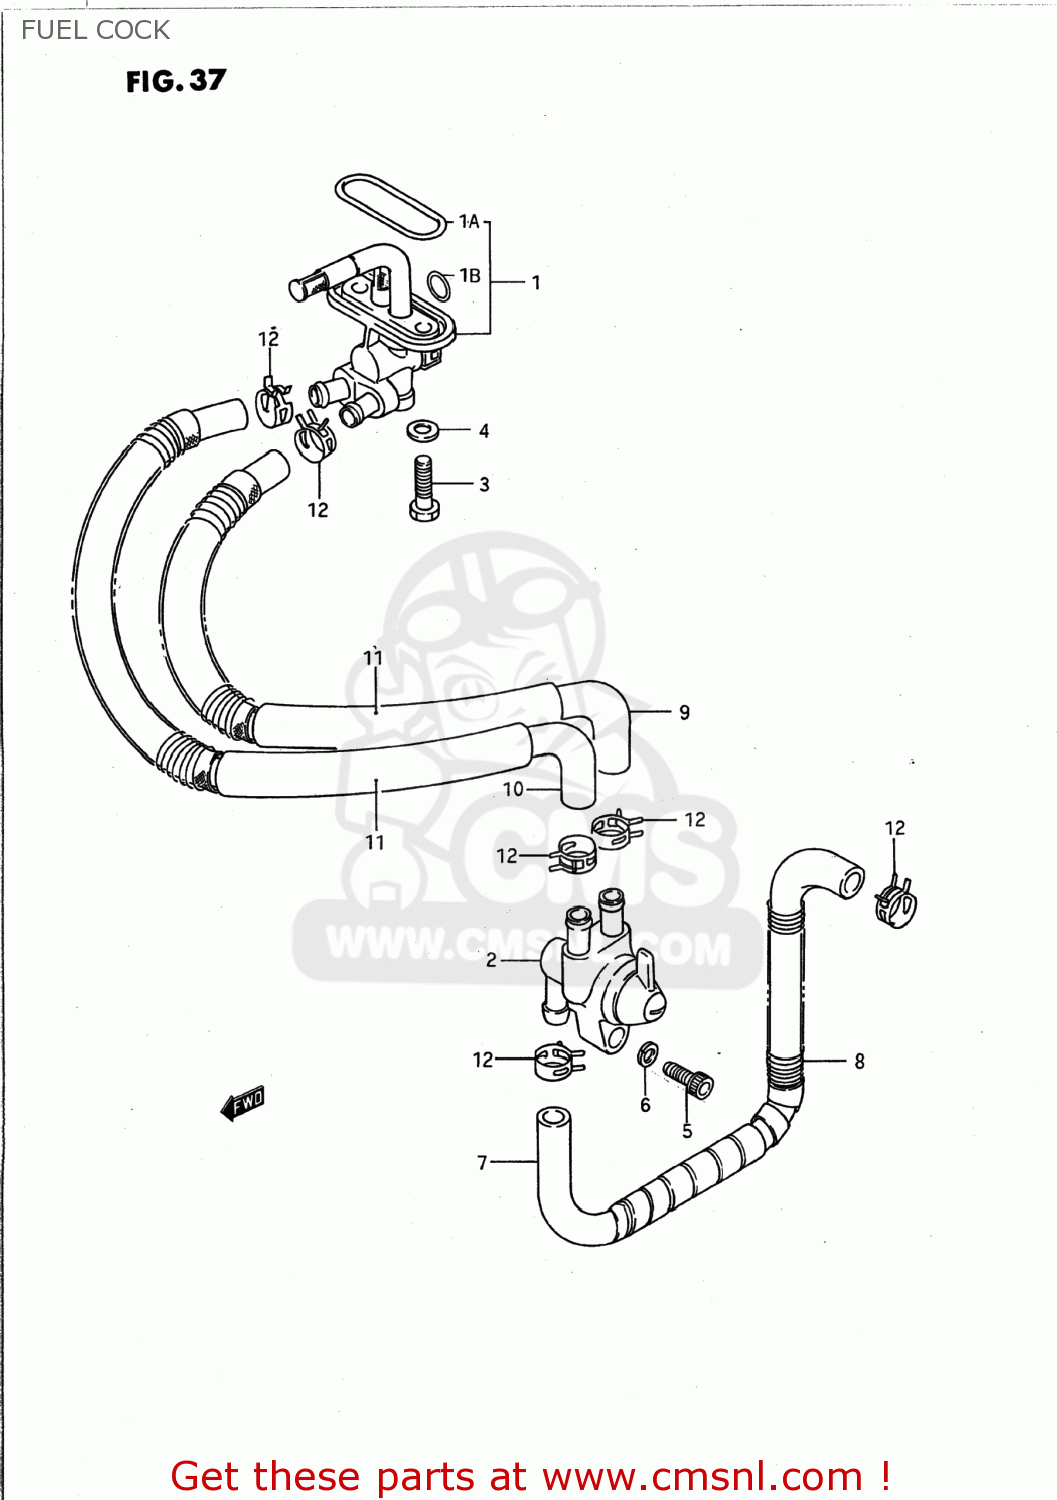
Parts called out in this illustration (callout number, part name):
1	COCK ASSY,FUEL
1A	O RING,FUEL COCK
1B	O-RING,LEVER
2	COCK ASSEMBLY,FUEL
3	BOLT(6X20)
4	GASKET(6.4X11.5X0.8) (NAS)
5	BOLT
6	WASHER,LOCK
7	HOSE COMP,FUEL PUMP &
8	SPRING
9	HOSE,FUEL
10	HOSE,FUEL
11	TUBE, FUEL HOSE
12	CLIP
